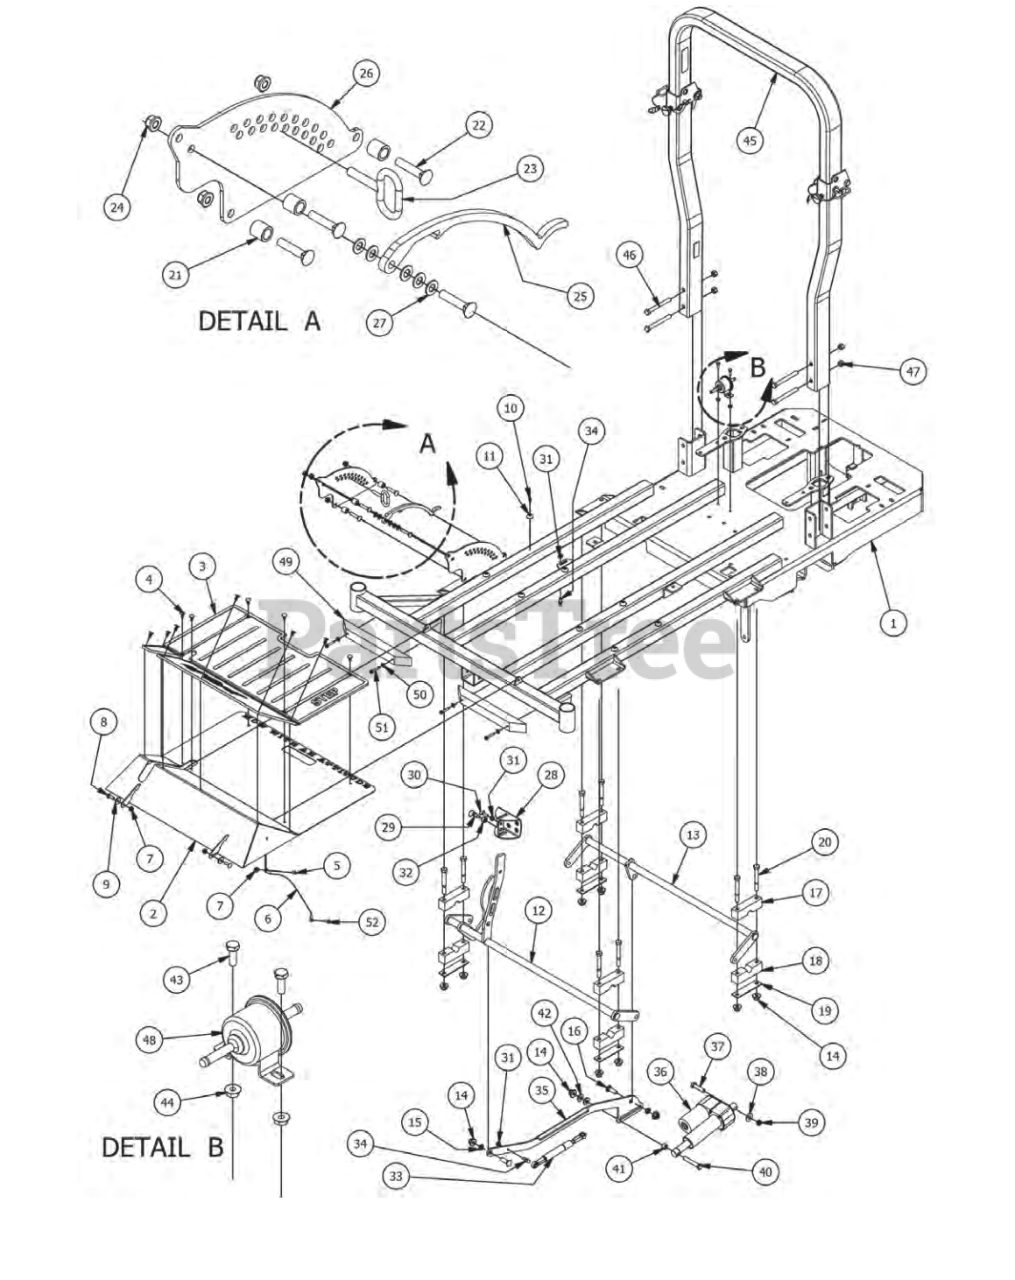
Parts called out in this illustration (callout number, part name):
1	Outlaw Diesel Frame 2012
2	Outlaw Floor Panel
3	Foot Assist Floor Mat
4	Ratchet Fastener
5	1/4" x 5/8" BS C/S 18-8 55
6	Floor board Cable W/ Swivel Ends
7	5/16" Flange Nut Zinc W/Serrations
8	5/16" x 1" Carriage Bolt
9	360 ID Plastic Washer
10	#10 x 1/2" Self Taping Screw
11	Button Bumper
12	2015 Outlaw Act Bar Assembly (Front)
13	2015 Outlaw Act Bar Assembly (Rear)
14	1/2-13 Nylon Flange Nut-Orange
15	Bushing-SF-1620-4
16	1/2 x 1-1/2 Carriage Bolt
17	Two Piece Pillow Block (Male)
18	Two Piece Pillow Block (Female)
19	Two Piece Pillow Block Strap
20	1/2" x 4" Bolt (Grade 8)
21	3/4 OD x 1/2 ID x 3/4 Length
22	3/8 x 13/4 Carriage Bolt
23	Deck height lever pin
24	3/8" Nylock Flange Nut
25	Outlaw Deck Lever Lock
26	Outlaw Height Indicator Plate (Outer)
27	390x.750 x 062 Nylon Washer
28	Outlaw Deck Lift Pedal
30	5/16-18 x1 Thumb Screw Zinc
31	5/16" Flange Nut
32	1/2" Hex Nut
33	250lb Gas Spring
34	10mm Damper Ball Stud-Steering
35	Outlaw Linkage Bar Susp Frame
37	1/2-13x2 Grade 8 Hex Bolt
38	1/2" Washer (Grade 8)
39	1/2" Nylcock Nut (1/2 Jam)
40	1/2" x 3" Hex Bolt
41	1/2 x 1/2 Spacer
42	505 Nylon Spacer
43	1/4" x 3/4" Hex Bolt
44	1/4-20 Hex Flange Nuts Zinc w/Serrations
45	2 X 3 ROPS Fits All 2012 Diesel Models
46	1/2" x 4 1/2" Bolt
47	1/2" Center Lock Nut
48	Electric Fuel Pump
49	14 Rubber Bumper
50	1/4" Flat Washer
51	1/4" x 1 1/2" Self Tapping Screw
52	1/4 x 1 Hex Head tek screw
